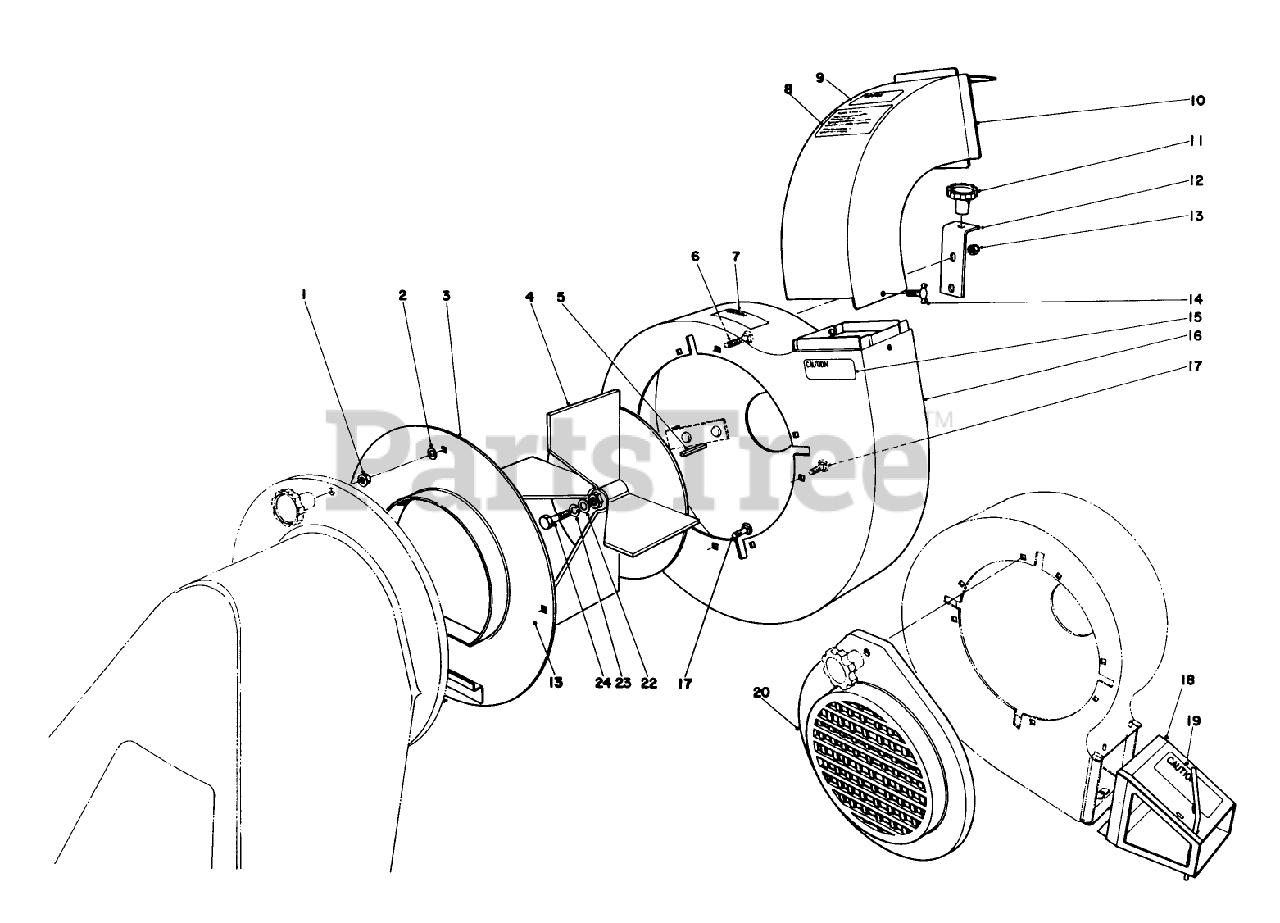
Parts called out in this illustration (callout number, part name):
1	NUT-FLANGE
2	WASHER-FLAT
5	KEY-SQUARE
6	SCREW-CARR
13	NUT-LOCK, CONE
14	1/4 - 20 3/4 WING SCR
17	BOLT-CARR
20	INTAKE-BLOWER
22	WASHER-FLAT
23	WASHER-LOCK
